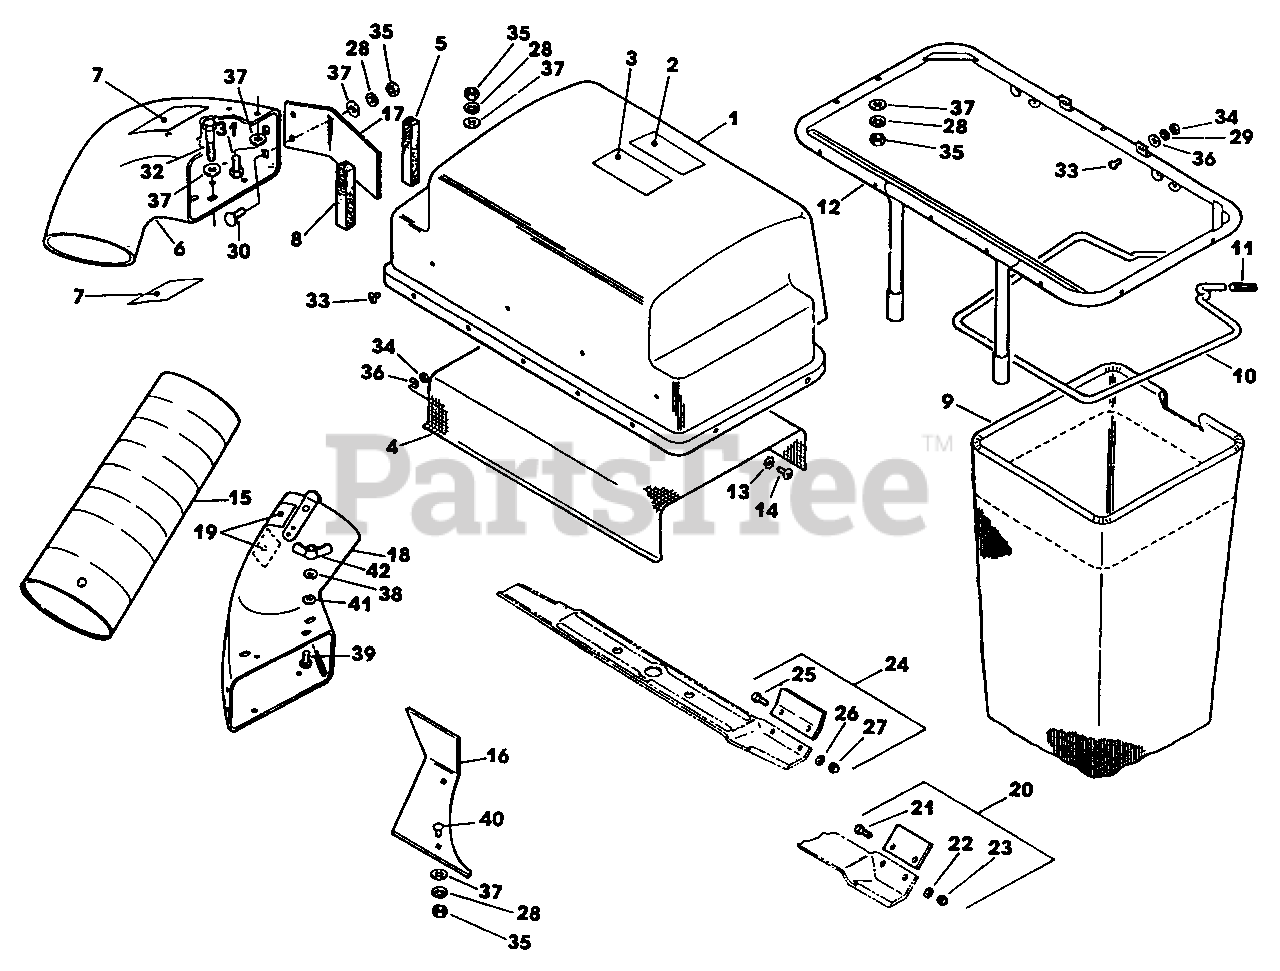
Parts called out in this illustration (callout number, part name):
1	Cover Assembly w/Decals
2	Decal-Warning
3	Decal-Warning
4	Screen
5	Foam Pad
6	Upper Chute Extension w/Decals
7	Decal-Danger
8	Foam Pad
9	Grass Bag
10	Grass Bag Frame
11	Grip
12	Hanger
13	Lockwasher, External Tooth
14	Screw, Self Tapping
15	Tube
16	Lower Chute Deflector
17	Upper Deflector
18	Lower Chute Extension w/Decals
19	Decal-Danger
20	Blade Extension Kit-Straight Blades
21	Screw, Hex Hd
22	Washer, Spring Lock
23	Nut, Hex Cone Lock
24	Blade Extension Kit-Angled Blades
25	Screw, Hex Hd
26	Washer, Spring Lock
27	Nut, Hex Cone Lock
28	Washer, Spring Lock
29	Washer, Spring Lock
30	Bolt, Carriage
31	Cap Screw, Hex Hd
32	Cap Screw, Hex Hd
33	Machine Screw
34	Nut, Hex
35	Nut, Hex
36	Washer, Flat
37	Washer, Flat
38	Washer, Spring Lock
39	Bolt, Carriage
40	Bolt, Carriage
41	Washer, Flat
42	Wing Nut
